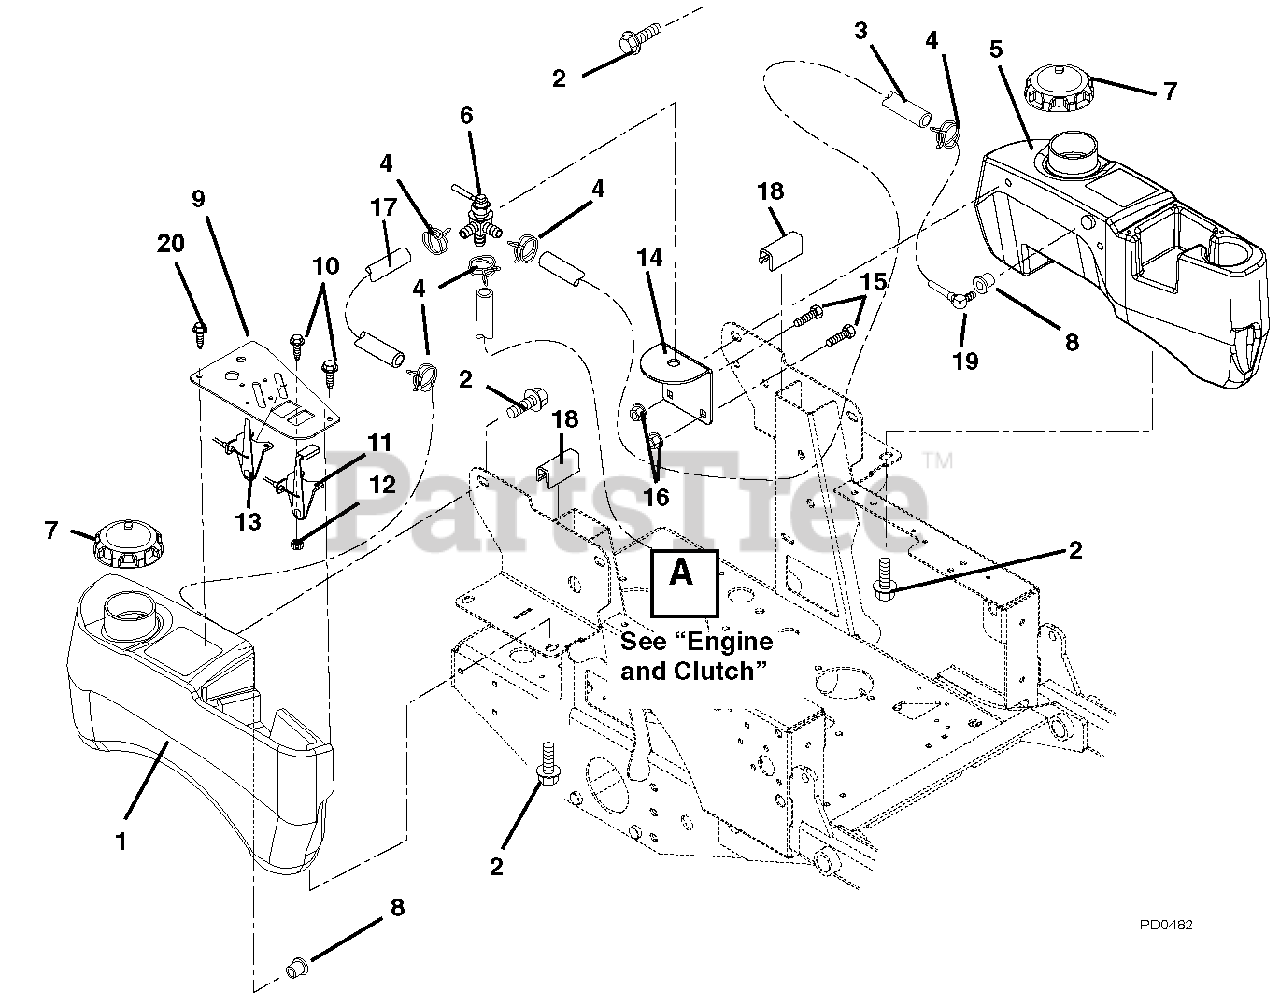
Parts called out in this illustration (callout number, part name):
1	Tank, Fuel Right Hand (S/N 101-2499)
2	Bolt, SEMS .31-18 x .62
3	Hose, Gas Line .25" I.D.
4	Hose, Clamp
5	Tank, Fuel Left Hand (S/N 101-2499)
6	Valve, Fuel
7	Cap, Fuel (S/N 101-2499)
8	Grommet (Orange color will not replace black color)
9	Panel, Control
10	Screw, Machine 10-24 x .50 Hex Washer Head
11	Cable, Throttle Choke
12	Nut, Locking Nylon 10-24 With Insert
13	Cable, Choke
14	Bracket, Fuel Valve Mounting
15	Bolt, Round Head Square Neck .31-18 x .75 Grade 5
16	Nut, Nyloc Flange 5/16-18
17	Hose, Gas Line .25" I.D.
18	Cowl Strip 1.75" Long
19	Assembly, Large Tank Fuel Pick-up
20	Screw, Machine 10-24 x .38
